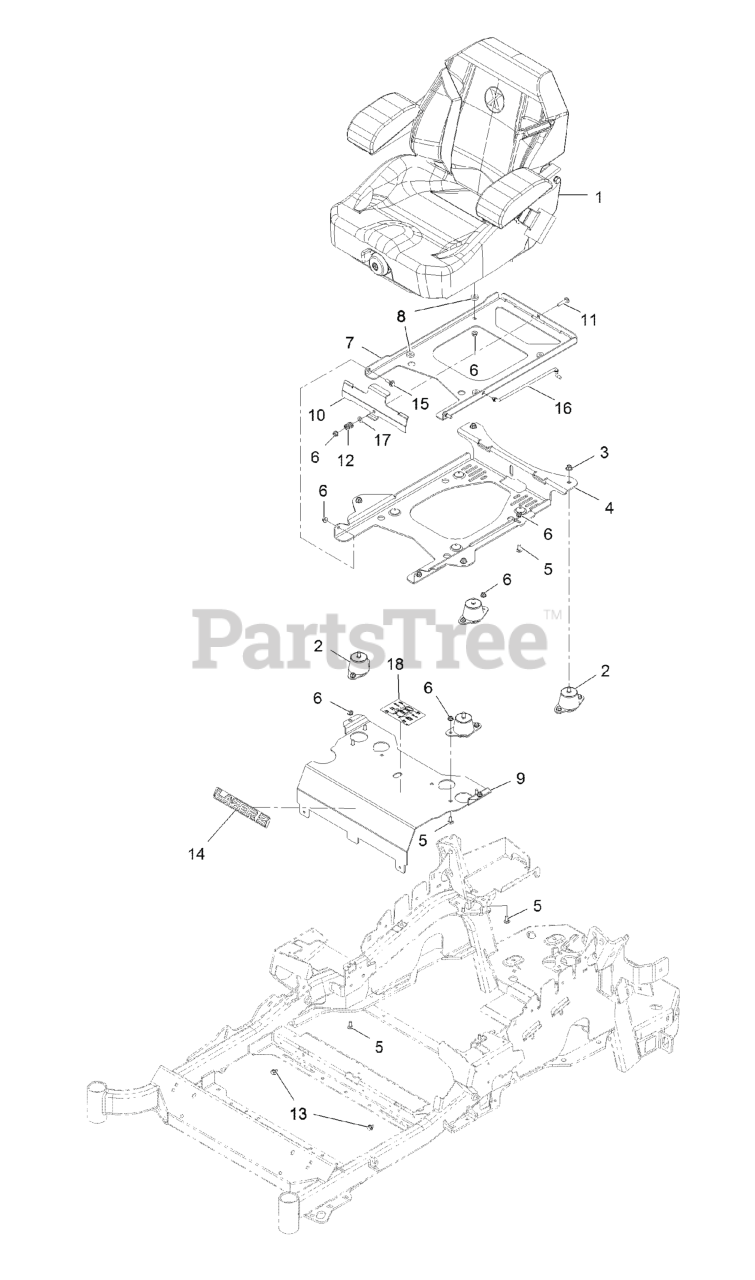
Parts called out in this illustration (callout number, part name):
1	KIT-SUSPENSION SEAT
2	ISOLATOR-SEAT
3	NUT-HF, NI
4	PLATE-TILT, SEAT SUPPORT
5	SCREW-CARR
6	NUT-HF, NI
7	PLATE-FRAME, SEAT
9	Panel-Front, Seat Mount
10	PLATE-LATCH, SEAT
11	BOLT-CARR
12	SPRING-COMPRESSION
14	DECAL, LAZER MODEL
15	SCREW-SHOULDER
16	ROD-PROP
17	WASHER-PLAIN
18	DECAL-SERVICE AID
